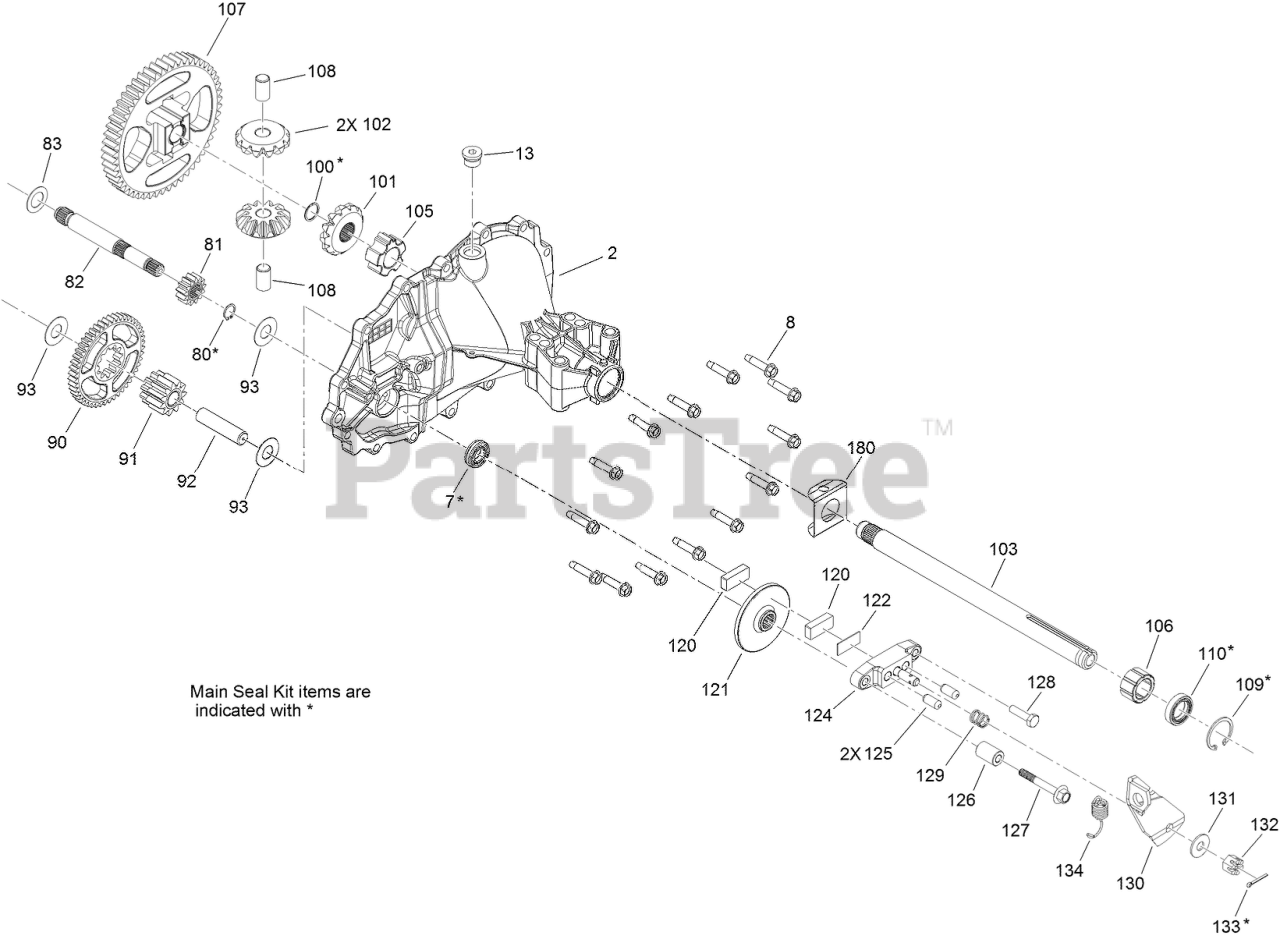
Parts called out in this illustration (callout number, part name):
2	HOUSING SIDE KIT
7	SEAL-LIP
8	SCREW-HHF
13	PLUG-THREAD, STRAIGHT
80	RING-RETAINING, EXTERNAL
81	GEAR-PINION
82	SHAFT-MOTOR
83	WASHER
91	GEAR-JACKSHAFT, 11T
92	PIN-JACKSHAFT
93	WASHER
100	RING-RETAINING, SPIRAL
101	GEAR-BEVEL, 12T (SPLINE, ID)
102	GEAR-BEVEL, 12T (.50 ID)
103	SHAFT-AXLE, KEYED
105	BUSHING-INBOARD
106	BUSHING-OUTBOARD
107	GEAR-53T, BULL
108	PIN-DIFFERENTIAL
109	RING-RETAINING, INTERNAL
110	SEAL-LIP
120	PUCK-BRAKE
121	ROTOR-BRAKE
122	PUCK-PLATE
124	YOKE-BRAKE
125	PIN-BRAKE
126	SPACER
127	SCREW-HF
128	SCREW-HHCS
129	SPRING-BRAKE, ANTI DRAG
130	ARM-BRAKE
131	WASHER
132	NUT-CASTLE
133	PIN-COTTER
134	SPRING-BRAKE, ARM
180	SPRING CLIP-HOUSING THRUST
